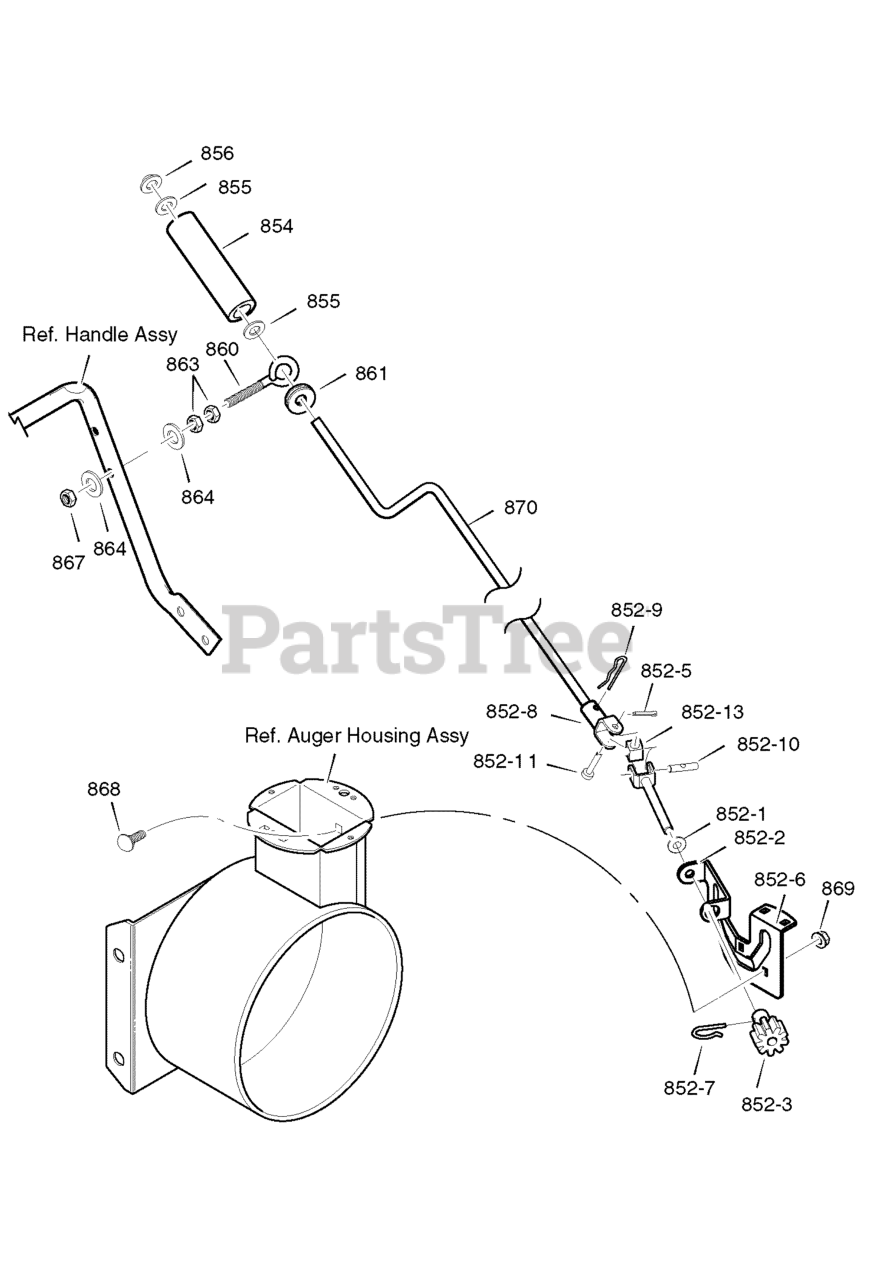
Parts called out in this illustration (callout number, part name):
852-1	ASSEMBLY, YOKE & ROD
852-2	WASHER, CURVED SPRING
852-3	GEAR, CHUTE ROTATION 9T
852-5	PIN, COTTER
852-6	BRACKET, GEAR MOUNT
852-7	PIN, HAIR
852-8	ASSEMBLY, YOKE ADAPTER YZ
852-9	PIN, HAIR
852-10	PIN, UNIVERSAL JOINT
852-11	PIN, CLEVIS
852-13	HOUSING, UNIVERSAL
854	KNOB, CRANK
855	FLATWASHER
856	NUT, PUSH
860	EYE BOLT 3/8-16X6.00
861	GROMMET, EYE BOLT
863	NUT, 3/8-16 HEXJAM
864	FLATWASHER .406X.81X.066
867	NUT, 3/8-16 HEXNYL
868	BOLT, CARRIAGE 1/4-20 X 1.00
869	NUT, 1/4-20 NYLOCK YZ
870	CRANK, ASSY CHUTE
